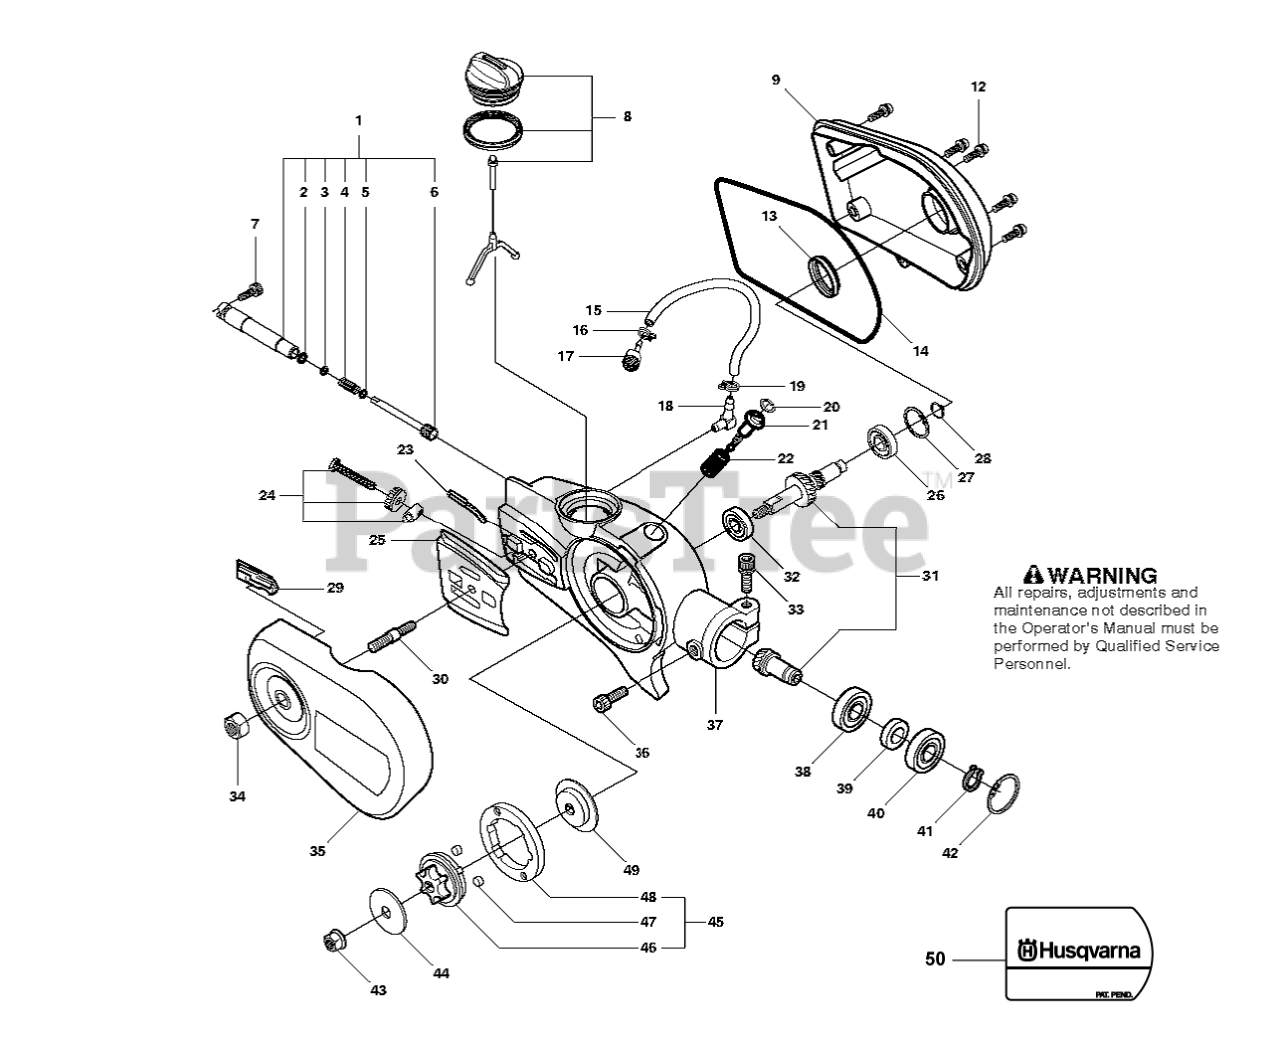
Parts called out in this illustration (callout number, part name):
3	WASHER 5.1X8.5
5	WASHER 5.1X8.5
6	%PUMP PISTON
7	SCREW MC6S 5X12
8	OIL TANK CAP GREY
12	SCREW MC6S 5X16
17	OIL PLUMMET
20	RETAINING RING
24	CHAIN TENSIONER
26	BALL BEARING
27	RETAINING RING SGH 26
28	RETAINING RING SGA 10
29	RP SEALING
32	BALL BEARING
33	SCREW MC6S 5X25
34	NUT
36	SCREW MC6S 5X12
38	BALL BEARING
39	SPACER SLEEVE
40	BALL BEARING
41	RETAINING RING
42	RETAINING RING
43	FLANGE NUT
44	FENDER WASHER
45	SPROCKET KIT
47	VIBRATION ABSORBER
